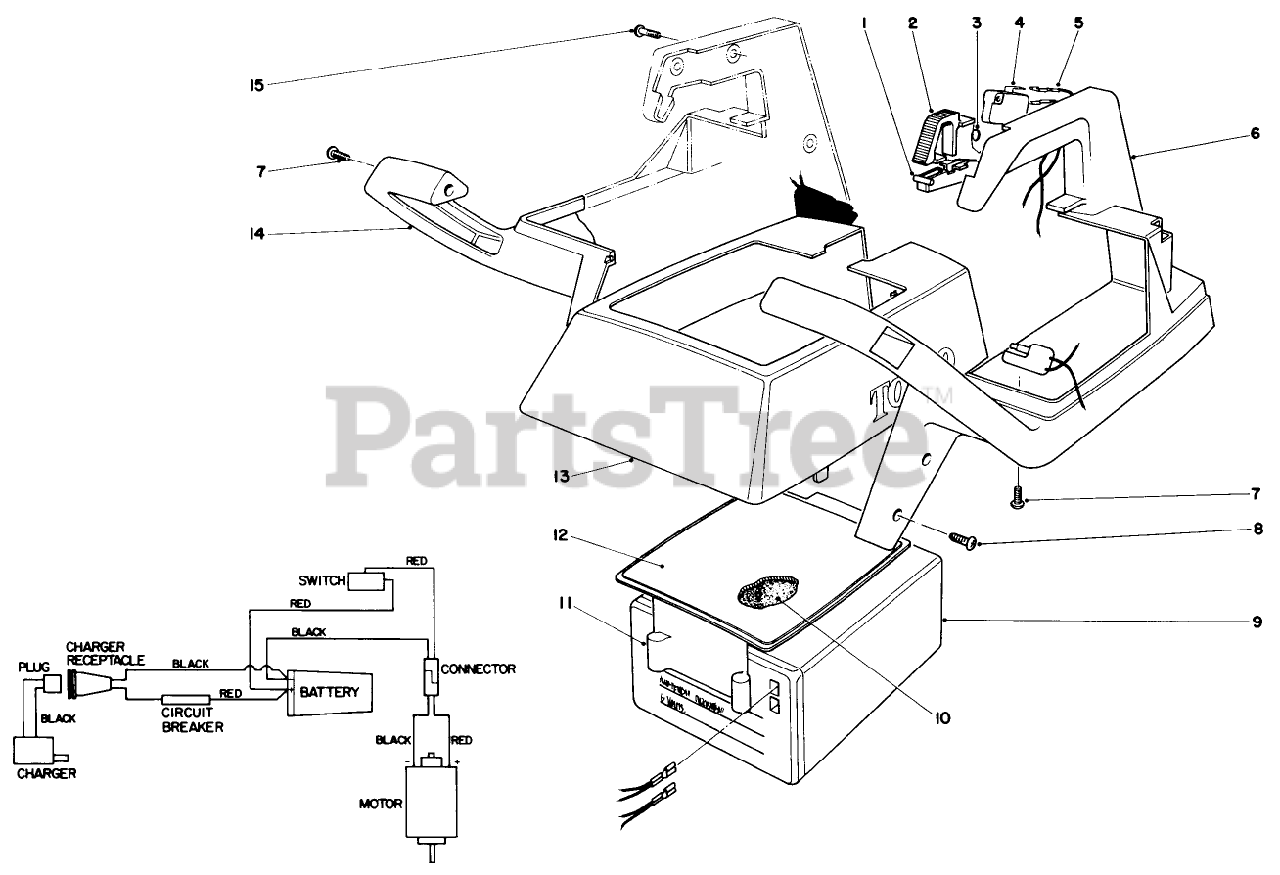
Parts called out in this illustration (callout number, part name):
3	SPRING
6	LH BATTERY CASE/HNDL
8	10-16 X .31 SCREW
12	Decal-Control Panel
15	SCREW-PPH
